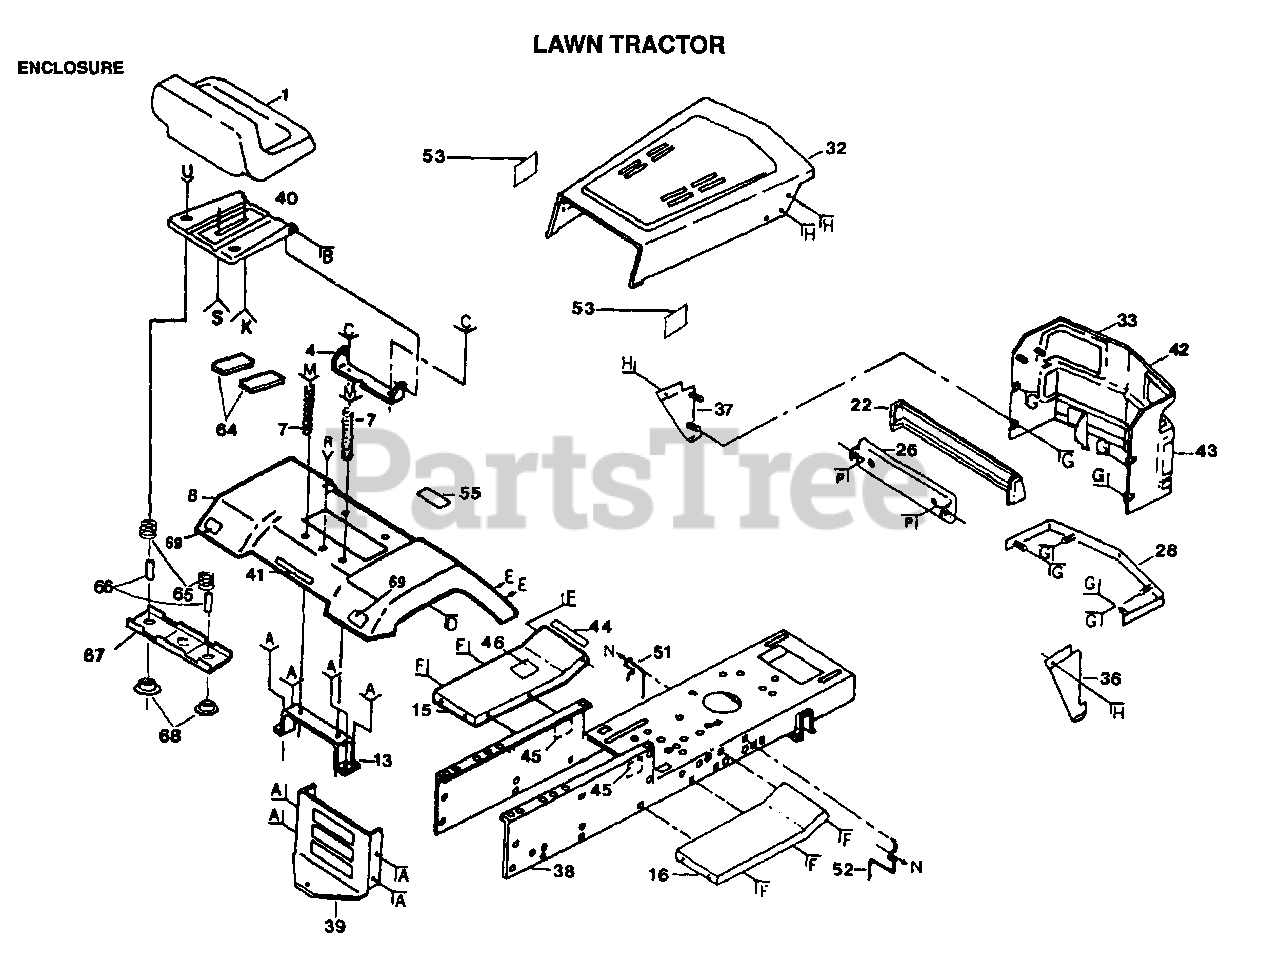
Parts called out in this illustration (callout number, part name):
2	SCREW
3	SCREW GTV
7	SPRING COMPRESSIO
9	WASHER
12	SCREW LT
15	FOOTREST LH
16	FOOTREST
17	BOLT
21	PAL NUT LT
24	WASHER
25	NUT
27	BOLT
38	CHASSIS ASS'Y
44	DECAL T
47	WASHER
48	LOCKWASHER
49	WASHER
50	BOLT
51	BELT GUIDE
52	BELT GUIDE
56	SCREW SPECIAL
59	WASHER
60	WASHER PM
62	BOLT
64	STRIP FORM
65	SPRING
66	SPACER SPLIT
67	BRKT SWITCH
68	BUSHING
69	REFLECTOR-TAIL YT
